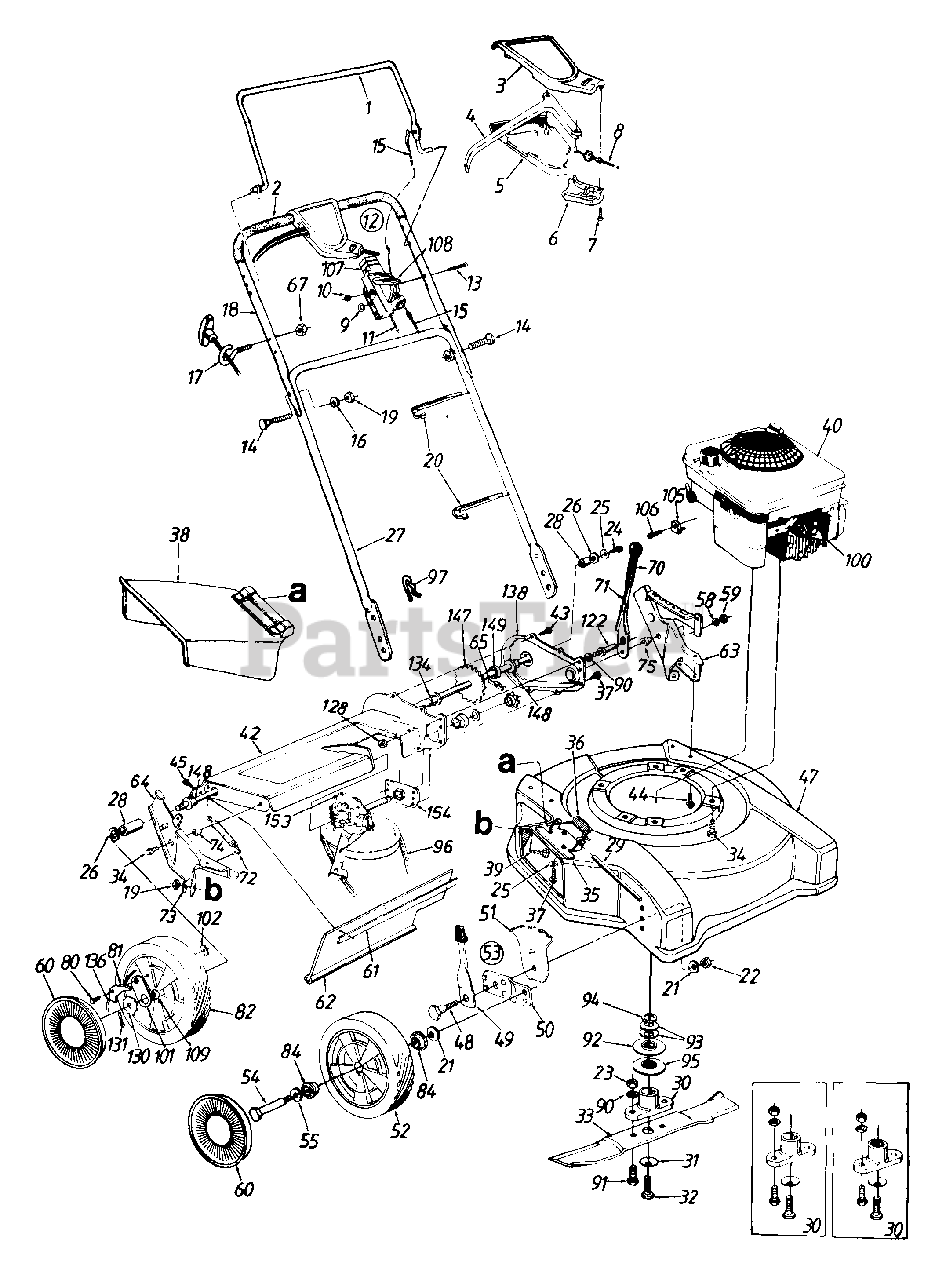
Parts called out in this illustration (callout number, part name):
2	Foam Grip
3	Upper - S.P. Control Cover
4	Control Lever
5	Lower - S.P. Control Cover
6	S.P. Control Cover
7	Fl-"C"-Sunk Hd. Tap Scr. #10 x .75" Lg.
8	S.P. Adj. Cable - 48" Lg.
9	Spr. Wash..66" I.D.
11	Throttle Control Wire 55"
12	Throttle Box Comp.
13	Oval C-Sunk Scr.
14	Curved Carr. Bolt 5/16-18 x 1.38"
15	Control Cable 39" Lg.
16	L-Wash. 5/16" I.D.
17	Rope Guide Bolt
18	Upper Handle
19	Hex Nut 5/16-18 Thd.
20	Cable Tie
21	Bell-Wash..38" I.D. x .88"
22	Hex Nut 3/8-16 Thd.
23	Hex Nut 3/8-24 Thd.
24	Hex Bolt 1/4-20 x .62" Lg. (Grade 5)
25	Bell-Wash. 1/4" I.D.
26	Fl-Wash..531" I.D. x .93"
27	Lower Handle
28	Spacer 513" I.D. x .703"
29	Hinge Pin
30	Blade Adapter Kit
31	Bell-Wash..39" I.D.
32	Hex Bolt 3/8-24 x 1.5" Lg.
33	22" Blade
34	Hex L-Wash. Hd. Scr. 3/8-16 x 1.0" Lg.
35	Adapter Plate
36	Torsion Spring
37	Hex Self-Tap Scr. 1/4-20 x .5"
38	Chute Deflector Ass'y.
39	Carriage Bolt 5/16-18 x .62" Lg.
40	Engine
44	Hex Wash. Hd. B-Tap Scr. 5/16-18
45	Hex AB-Tap Scr. 1/4 x .62"
49	Spring Lever Ass'y. w/Knob
50	Pivot Bar
51	Height Adj. Plate
52	Front Wheel Ass'y. Comp.
53	Height Adj. Ass'y. Comp.- R.H.
54	Shld. Bolt .498" Dia. x 1.45"
55	Wave Wash..53" I.D. x .78"
58	Fl-Wash..385" I.D. x .87"
59	Hex Patch L-Nut 3/8-24 Thd.
60	Hub Cap
61	Retaining Strip
62	Rear Flap
63	L.H. Handle Wheel Brkt. Ass'y.
64	R.H. Handle Wheel Brkt. Ass'y.
65	#48 Chain .5" Pitch x 30 Links
67	Hex L-Nut 1/4-20 Thd.
71	Height Adj. Lever
72	Ext. Spring .5" O.D. x 3.8" Lg.
73	Bell-Wash. 5/16" I.D.
74	Spacer 383" I.D. x 503"
75	Shld. Spacer .5" Dia.
80	Shld. Scr..342" Dia. x .268"
81	Pawl
82	Rear Wheel Ass'y. Comp.
84	Ball Bearing 1/2" I.D.
90	L-Wash. 3/8" I.D.
91	Hex Bolt 3/8-24 x 1.0" Lg.
92	Splined Pulley Half
93	Bell-Wash. 1.01" I.D.
94	Crankshaft Spacer
95	Lower Pulley Half
96	"V"-Belt
97	Hairpin Clip
100	Spark Plug Boot
101	Pawl Plate
102	Weld L-Nut 1/4-20 Thd.
105	Cable Clamp
106	Hex Self-Tap Scr. #10-32 x .62"
107	Throttle Body
108	Throttle Lever
109	Sleeve Brg. 1/2" I.D.
122	Shld. Pin 3/8-24 x 1.43" Lg.
128	Hex Jam Nut 3/8-24 Thd.
130	Ratchet Wheel 1.62" O.D.
131	Cotter Pin 1/8" Dia.
134	Hex Flange Bearing
136	Spring - Nylon
148	Hex Flange Bearing
149	Fl-Wash..531" I.D. x .93"
153	Transmission Comp.
154	Hex Bearing Cup
